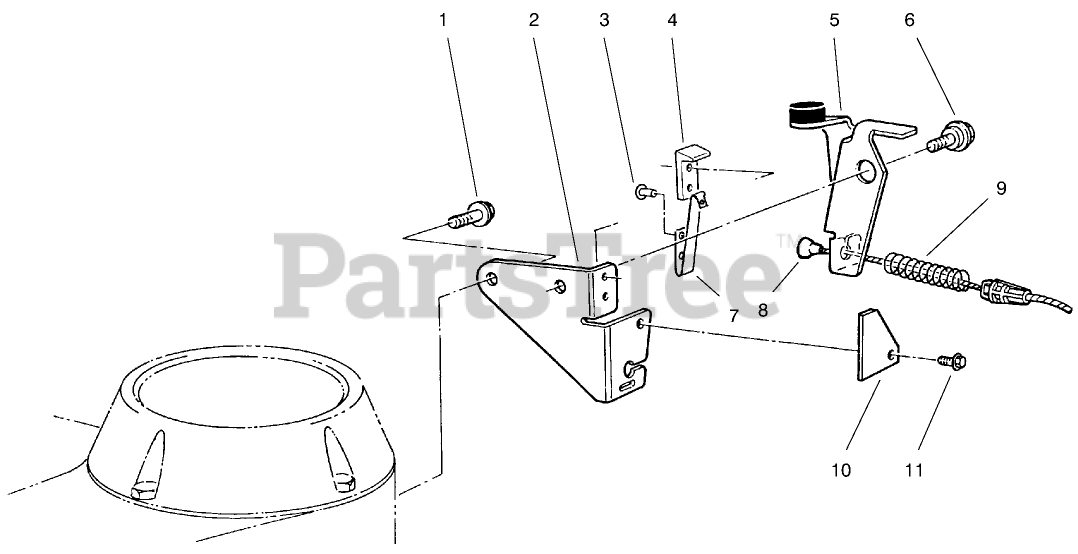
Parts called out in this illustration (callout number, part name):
1	SCREW-HWH
2	PLATE-BRAKE
3	RIVET-PLASTIC
4	STRAP-INSULATING
5	BRAKE PLATE ASM
6	SCREW-SHOULDER
7	STRAP-GROUND
8	BRAKE CABLE
9	SPRING-COMPRESSION
10	STOP-GROUND STRAP
11	SCREW-HWH
